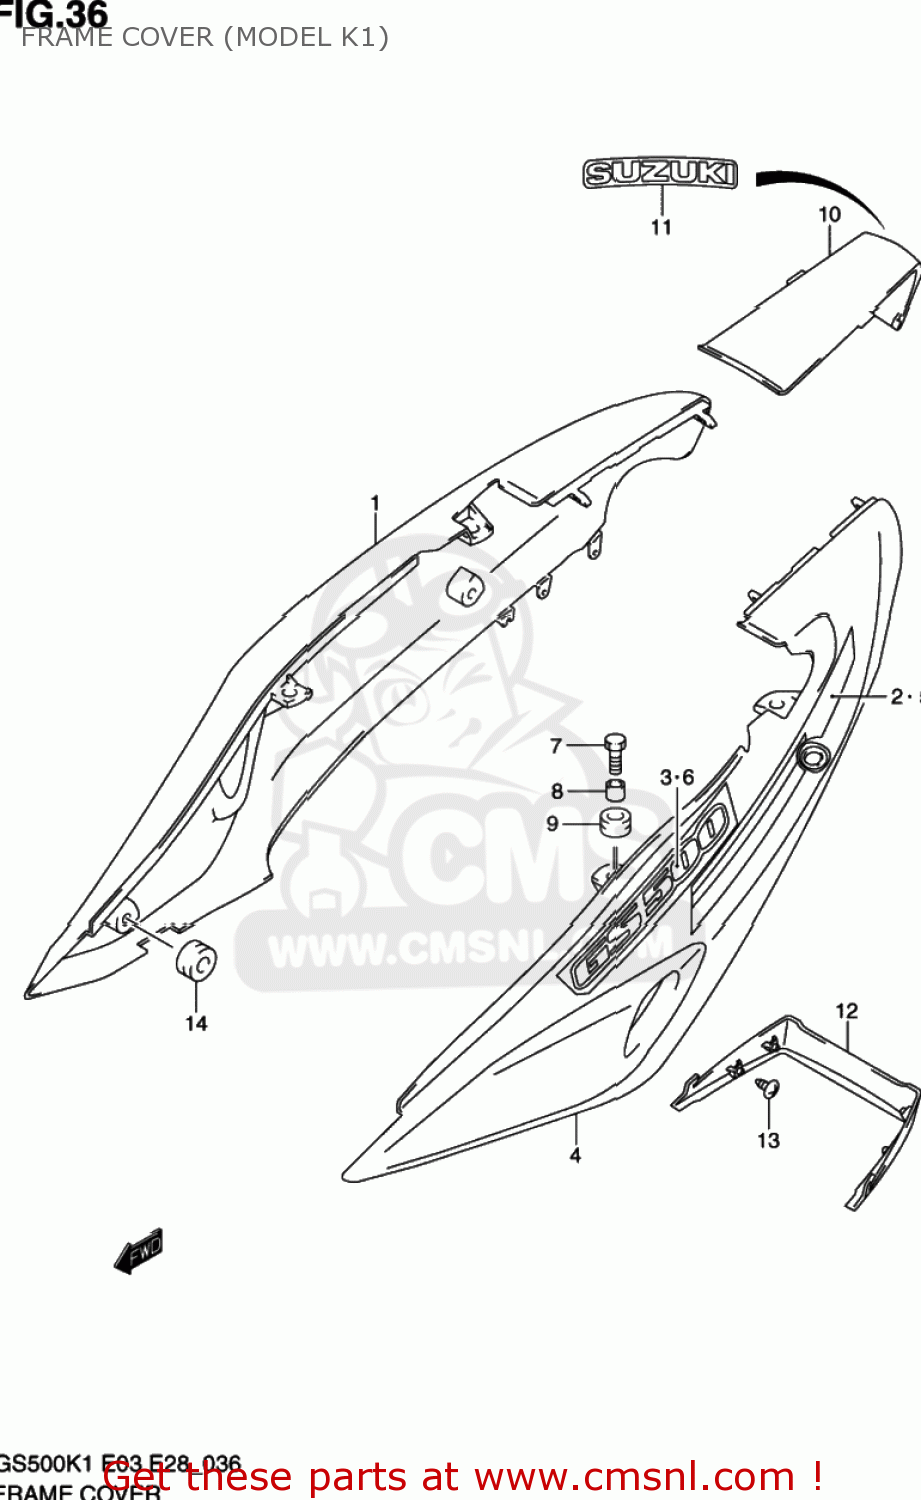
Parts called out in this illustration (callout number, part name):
1	COVER,FRAME,R(BLUE)
2	TAPE,FRAME COVER,R
3	EMBLEM,FRAME COVER
4	COVER,FRAME,L(BLUE)
5	TAPE,FRAME COVER,L
6	EMBLEM,FRAME COVER
7	BOLT(6X20)
8	SPACER(6.5X9X9)
9	CUSHION
10	COVER,FRAME CTR
11	EMBLEM,SUZUKI
12	COVER, FRAME LOWER
13	SCREW
14	CUSHION
